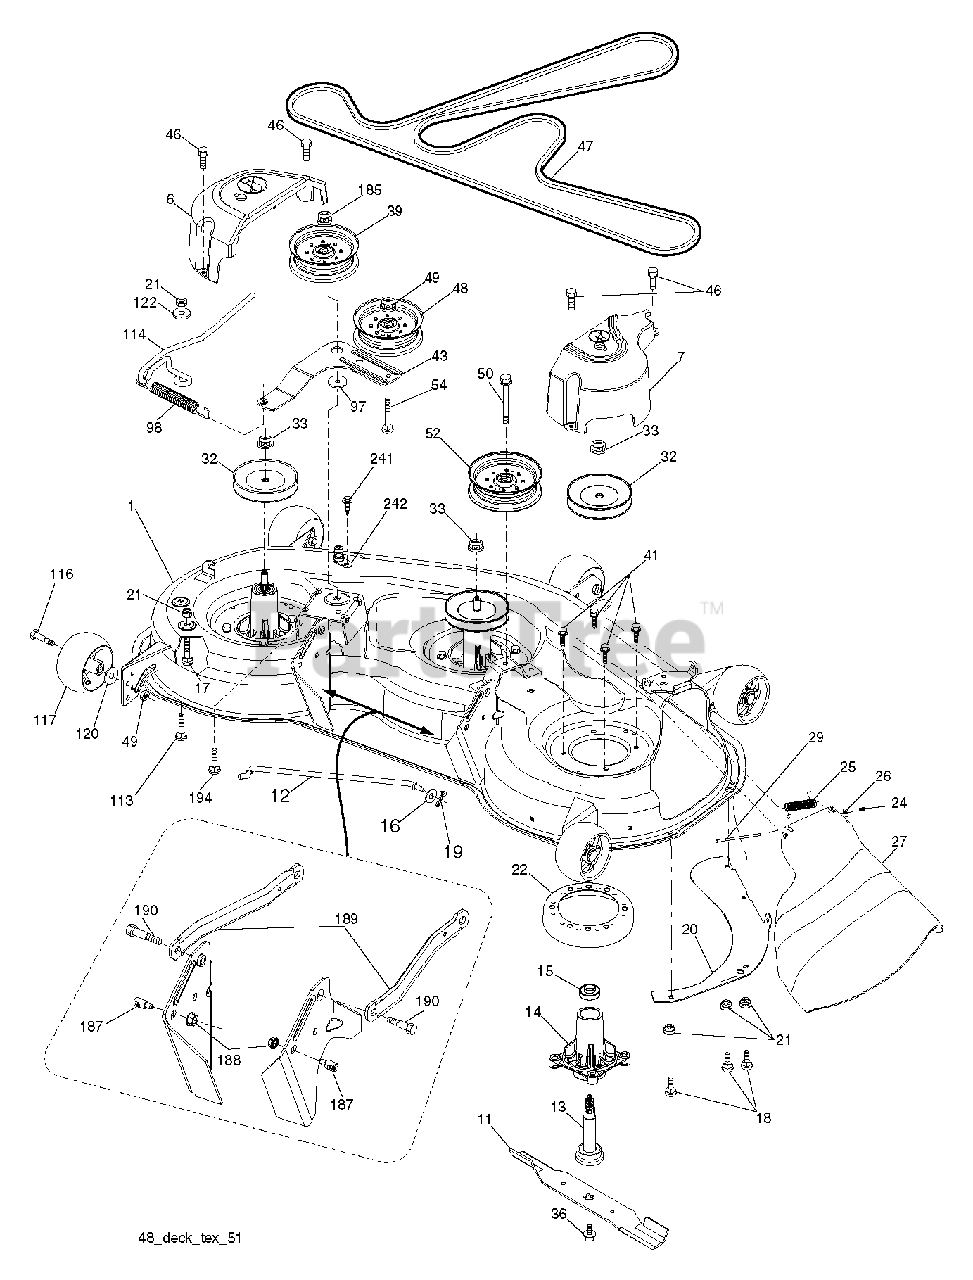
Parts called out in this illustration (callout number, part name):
1	DECK SVC 48"TEX.
6	COVER.MANDREL.LH.48"
7	COVER.MANDREL.RH.48"
11	48" HI-LIFT BLADE
12	ROD.ANTI.SWAY.48/54"K4
13	Mandrel Assembly, Greaseable
14	HOUSING.MANDREL.4PT.
15	Extended Mandrel Bearing, Top
16	WASHER
17	BOLT
18	BOLT
19	PIN.COTTER.5/16.BOW TI
20	BAFFLE, VORTEX MWR
21	LOCKNUT
22	STRIPPER.MANDREL.ROUND.BLACK
24	CAP-SLEEVE LT
25	SPRING, TORSION
26	NUT PUSH M
29	ROD.HINGE
32	PULLEY MANDREL
33	NUT.FLANGE.LOCK.TOP
36	Screw, 7/16 X 20 X 1"
39	PULLEY.IDLER.4.50/HUB SPECIAL
41	Hex Washer Head Bolt, .313-18 X 1.19
43	ARM.IDLER
46	SCREW.1/4-20X5/8
47	BELT.DRIVE.DECK
48	PULLEY.IDLER.2006
49	NUT LOCK FLG 3/8-16 UNC
50	SCREW TT 3/8-16X2-1/4 UNC
52	PULLEY.IDLER.48"PRIMARY
54	BOLT.3/8-16X1.50
98	SPRING, DECK DRIVE
113	BOLT CRT
114	ROD.TENSION.RELIEF.TEX (2 2)
116	BOLT.SHOULDER.3/8-16X3-5/8.
117	WHEEL. GUAGE RALLY
122	BUSHING.RELIEF.TENSION
185	NUT.LOCK.FLANGE.7/16
187	STUD.FASTNER.W/ANTI-ROTATE
188	NUT LOCK HEX FLANGE 5/16-18
189	ARM.SUSPENSION.MOWER
190	BOLT.SHOULDER
194	BOLT.HEX.WASHER.HEAD.7/16-24X
241	SCREW.TT.#10-32X.5.3/8.FLANGE
242	PORT.WASHOUT
